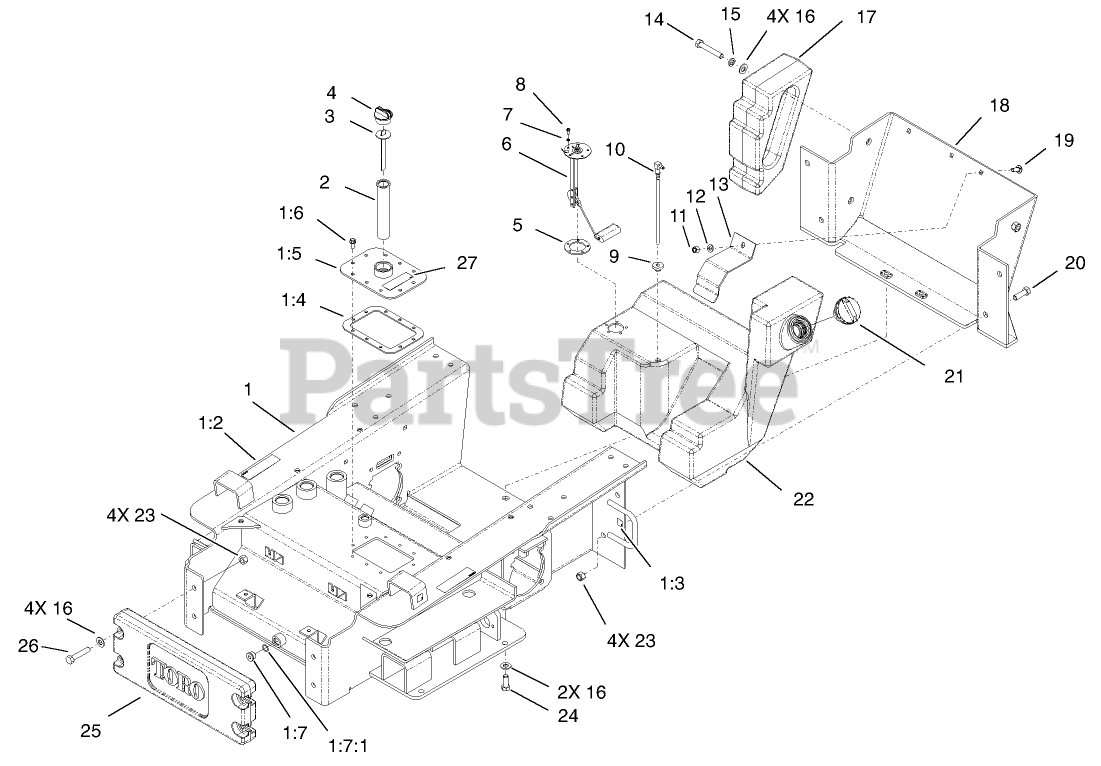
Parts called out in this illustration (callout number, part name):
1	MAIN CHASSIS ASM
1:2	DECAL-PINCH
1:3	DECAL-POINT, LIFT
1:4	GASKET-COVER, ACCESS
1:5	TANK COVER ASM
1:6	SCREW
1:7	PLUG-HEX
1:7:1	O-RING
2	FILTER-SCREEN
3	DIPSTICK-OIL
4	PLUG-PLASTIC
5	GASKET-SENDER, FUEL
6	SENDER-FUEL
7	WASHER-LOCK
8	SCREW-PPH
9	BUSHING
10	PIPE-STAND
11	NUT-LOCK, NI
12	WASHER-FLAT
13	CLAMP-TANK, FUEL
14	SCREW-HH
15	WASHER-LOCK
16	WASHER-FLAT
17	COUNTERWEIGHT-REAR
18	REAR FRAME COVER ASM
19	SCREW-CARR
20	SCREW-HH
21	CAP-FUEL
22	TANK-FUEL
23	NUT-LOCK, NI
24	SCREW-HH
25	COUNTERWEIGHT-FRONT
26	SCREW-HH
27	X-REF 105-8404
